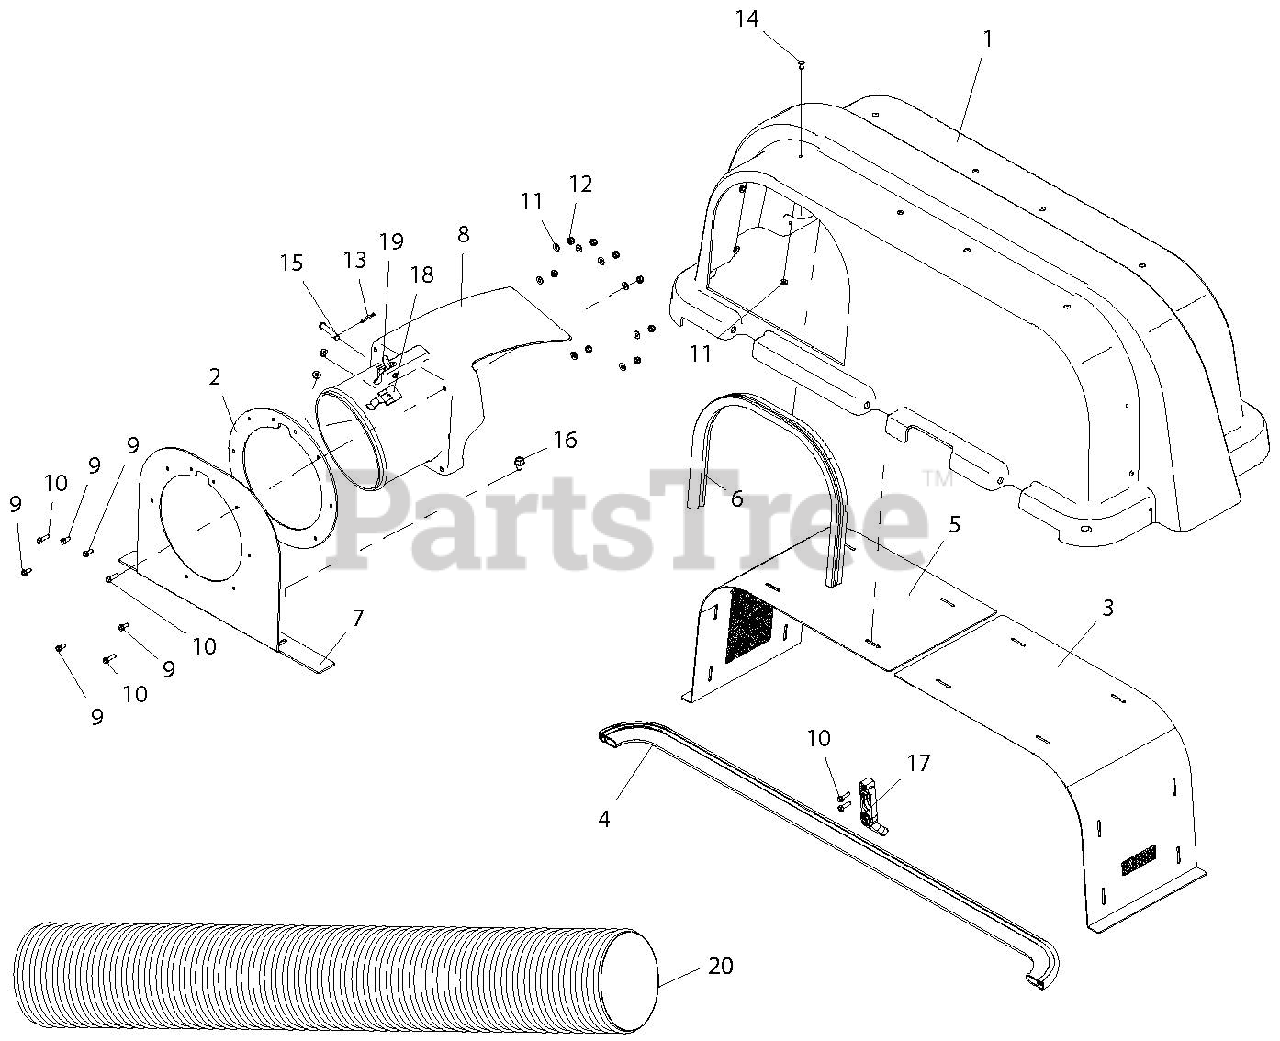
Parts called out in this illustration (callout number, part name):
1	COVER, 2-BUCKET BAGGER
2	SEAL, UPPER BOOT
3	WLDMT, BAGGER HOOD VENT, LH
4	SEAL, BULB - BAGGER HOOD
5	WLDMT, BAGGER HOOD VENT, RH
6	SEAL, BULB
7	WLDMT, TUBE SUPPORT
8	BOOT, UPPER
9	SCR-MCH 10-24X.50 HWH YWZC
10	SCR-MCH 10-24X.75 HWH YWZC
11	WSHR-FL-STL
12	NUT-LK-NYL #10-24 YWZC
13	PIN-HAIR, ENDRIES #25 YWZC
14	RVT-POP .187x.375
15	PIN, CLEV .309X1.62 YWZC
16	SCR-TAP .31-18X.50 HWH TR YWZ
17	LATCH, RUBBER
18	LATCH, THUMB
19	INDICATOR, FLOW
20	BAGGER TUBE
